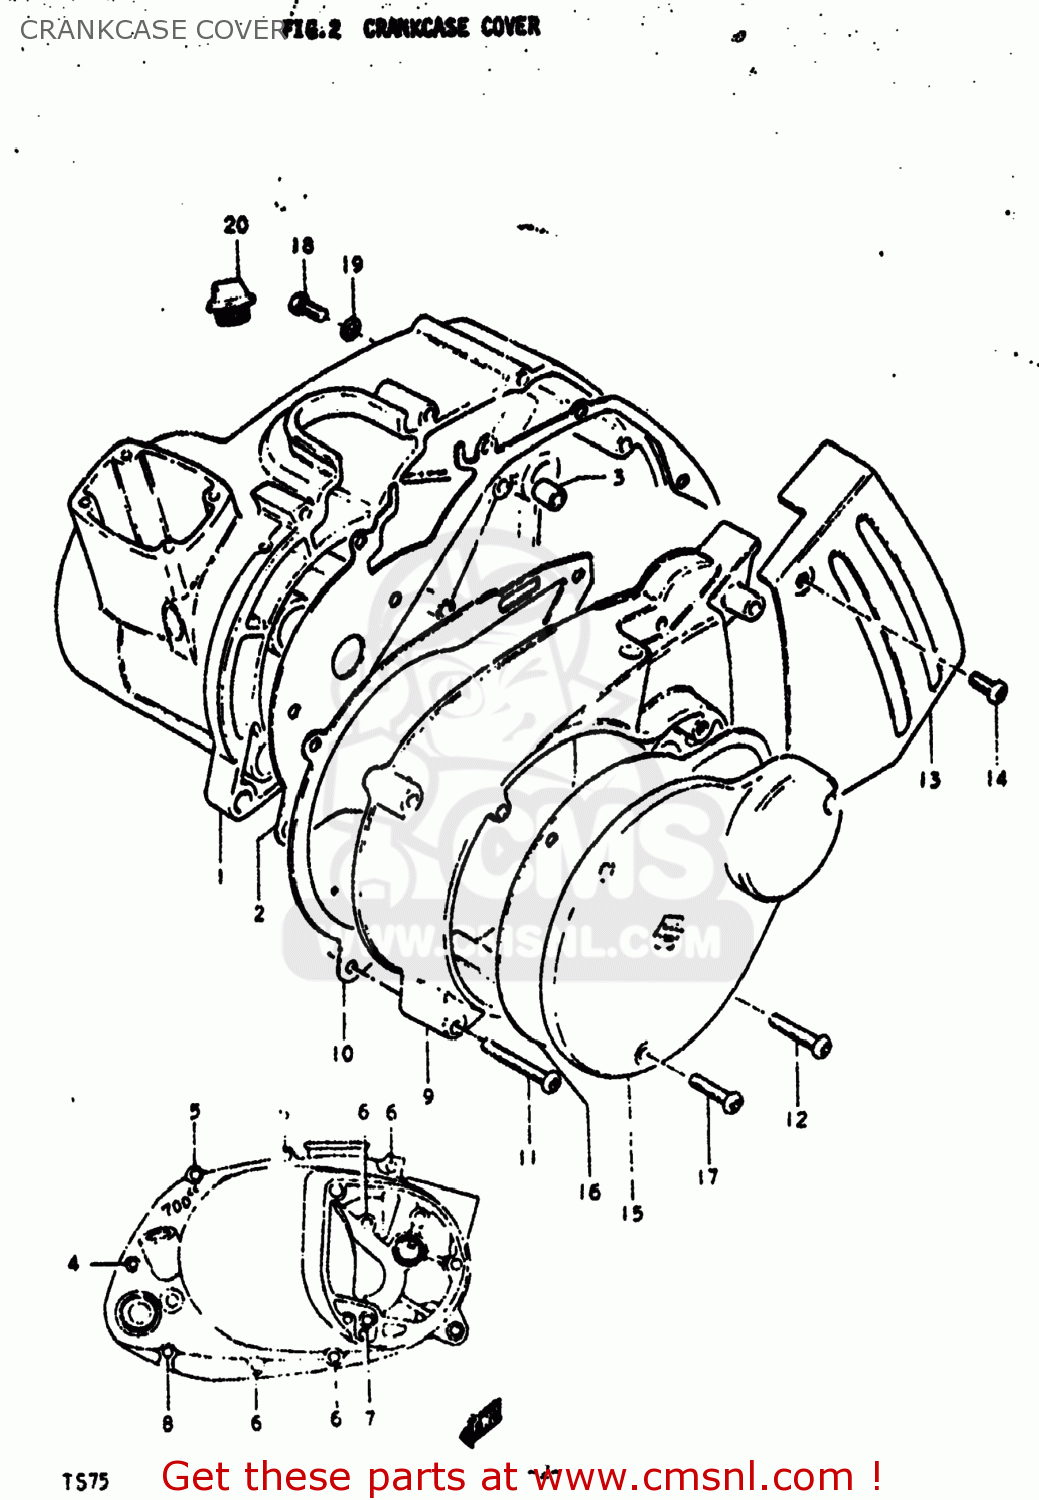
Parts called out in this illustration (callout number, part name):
1	COVER,CLUTCH
2	GASKET,CLUTCH COVER (MCA)
3	PIN
4	SCREW 6X70
5	SCREW
6	SCREW (6X35)
7	SCHROEF 5X80
8	SCREW
9	COVER
10	GASKET,MAGNETO COVER (NAS)
11	SCREW (6X35)
12	SCREW
13	COVER,SPROCKET
14	SCREW
15	COVER,SIGNAL GENERATOR
16	GASKET (MCA)
17	SCREW
18	SCREW(6X10)
19	GASKET(6.2X11X1) (NAS)
20	PLUG
